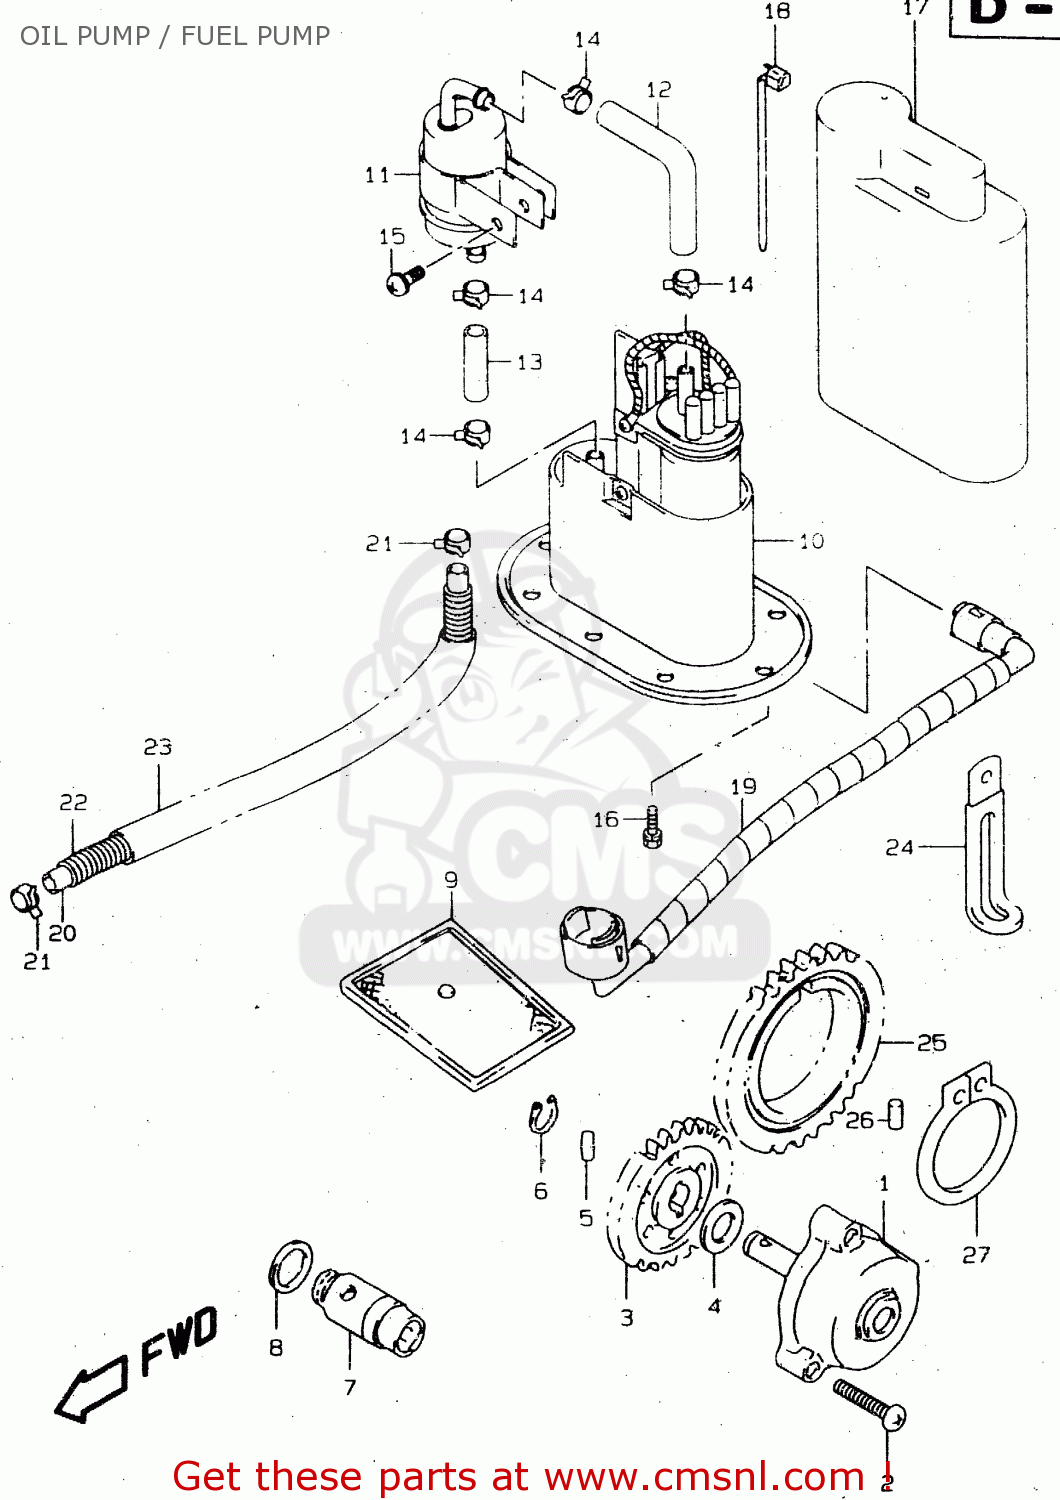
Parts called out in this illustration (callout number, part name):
1	PUMP ASSY,ENGINE OIL
2	SCREW
3	GEAR,OIL PUMP DRIVEN
4	SHIM(10X18X0.5)
5	PIN(4X15.8)
6	CIRCLIP,10MM
7	VALVE ASSY,OIL RELIEF
8	GASKET(16X22X2) (NAS)
9	STRAINER,ENGINE OIL
10	PUMP ASSEMBLY,FUEL
11	FILTER,FUEL
12	HOSE,FUEL
13	HOSE(7.6X14X600)
14	CLIP
15	SCREW
16	BOLT
17	COVER,FUEL PUMP
18	CLAMP(L:125)
19	HOSE,FUEL
20	HOSE(5.4X11.4X600)
21	CLIP
22	(CA) SPRING
23	PROTECTOR,FUEL RETURN NO,2
24	CLAMP(L:65)
25	GEAR,ENG OIL PUMP DRIVE
26	PIN(6X6)
27	CIRCLIP
